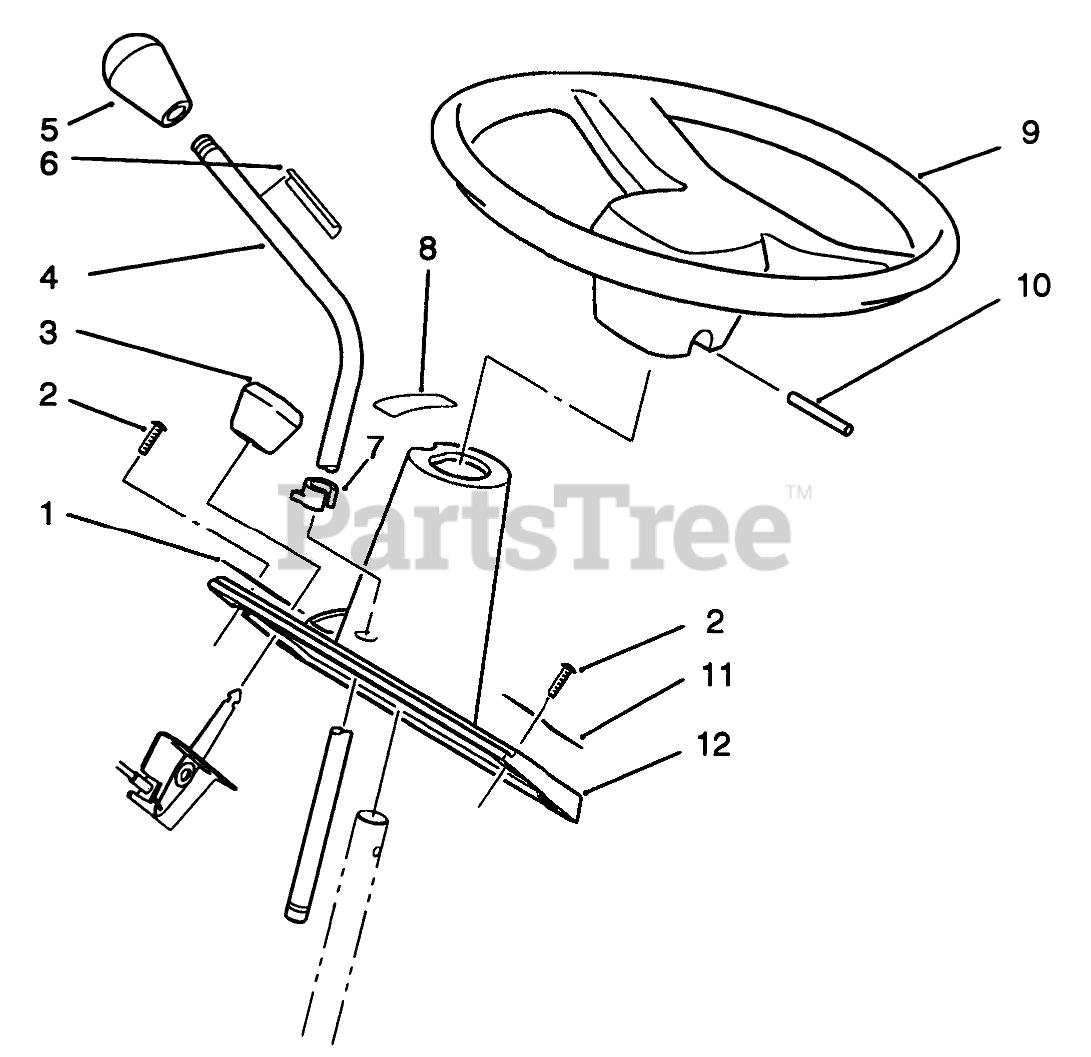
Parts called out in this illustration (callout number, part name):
1	DECAL-THROTTLE
2	SCREW
3	KNOB-THROTTLE
4	ROD-SHIFT LEVER
6	DECAL-MOTION CONTROL
7	POINTER
8	DECAL-HYDRO MOTION
9	Steering Wheel
10	PIN-ROLL
11	Decal-Height of Cut
12	CONSOLE
